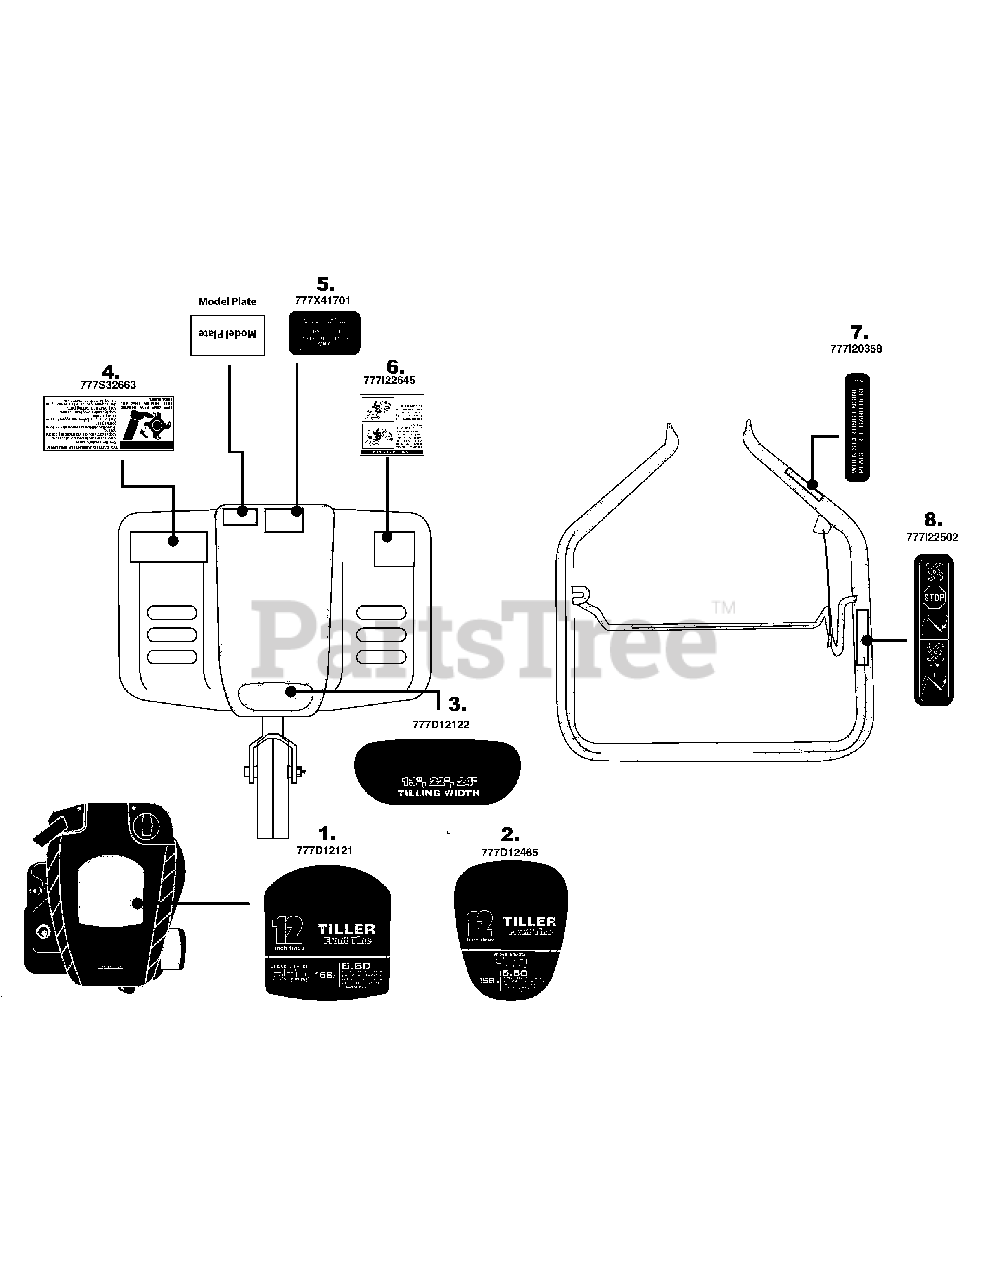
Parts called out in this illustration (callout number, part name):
1	LABEL-TILLER SHROUD BOLENS
2	LABEL-TILLER SHROUD BOLENS
3	LABEL-TILLER TINE SHIELD BOLENS
4	LABEL-TILLER TINE SHIELD:WARNING
6	LABEL-TILLER FRNT/WHL DO NOT TILL
7	LABEL-PLACE HAND HERE
8	LABEL:TILLER HANDLE:ENGAGE
